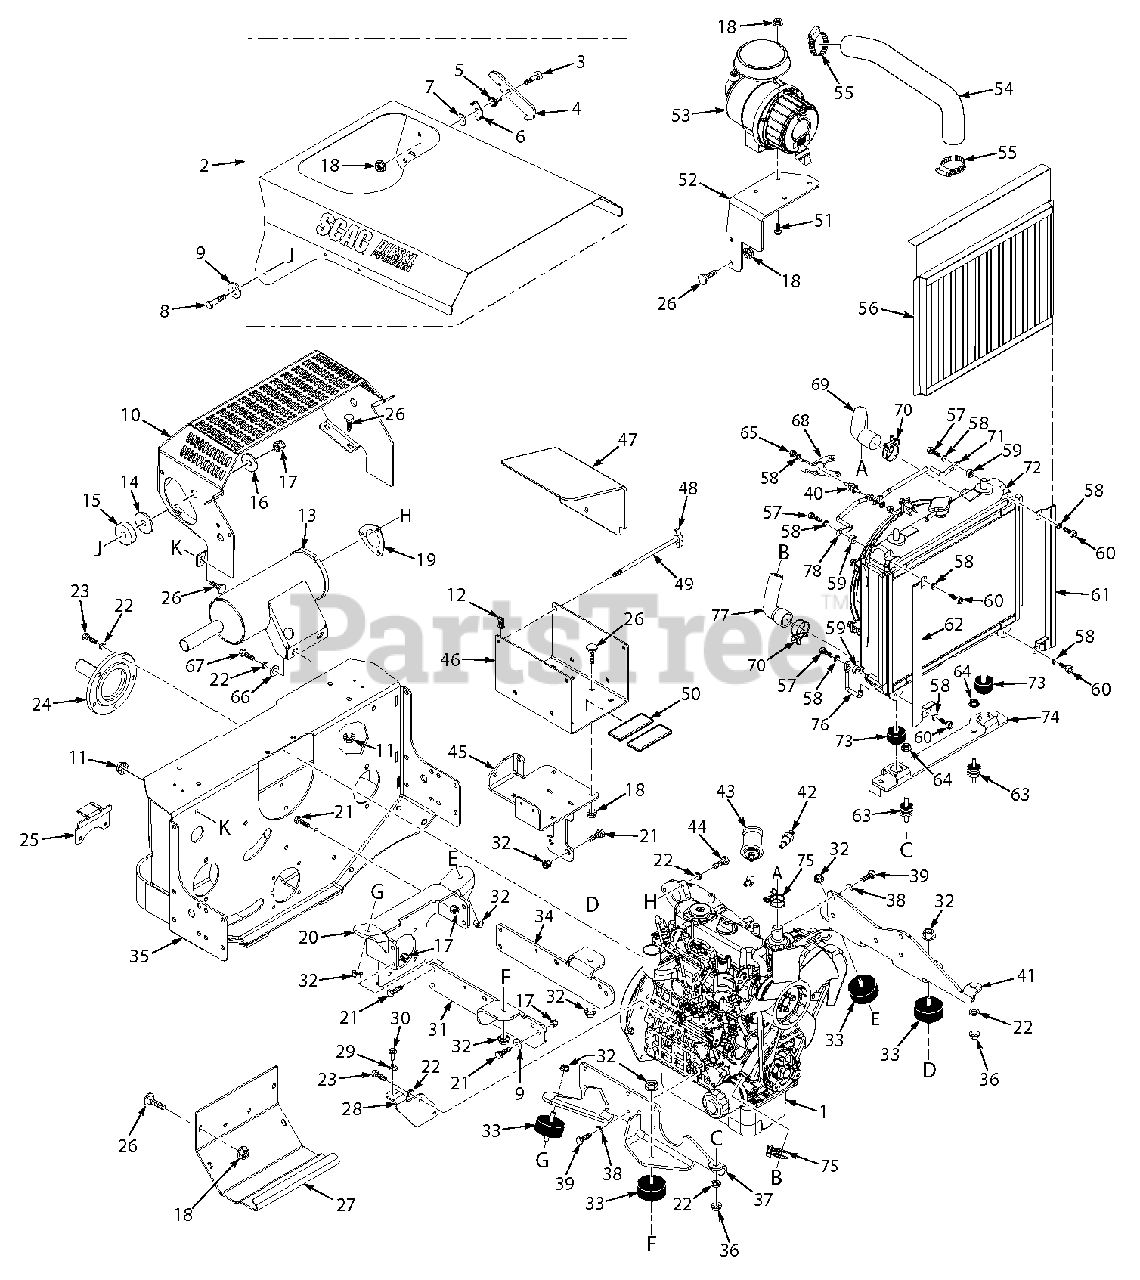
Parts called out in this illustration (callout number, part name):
1	Engine, D902 - Kubota
2	Hood Assy., STTII (Kubota Diesel)
3	Bolt, Shoulder 5/16-18 x 1/2"
4	Latch, Hood
5	Spring, Hood Latch
6	Lock, Hood Latch
7	Flatwasher, 3/8-.406 x .812 x .065
8	Bolt, Hex Head, 3/8-16 x 1-3/4"
9	Flatwasher, 3/8-.391 x .938 x .105
10	Guard, Muffler
11	Nut, Flange Elastic Stop Nut, 5/16-18
12	U-Nut 1/4-20
13	Muffler, Kubota
14	Disc, Anti-Friction
15	Spacer, Hood
16	Flatwasher, 3/8 (.406 x 1.50 x 7 Ga.)
17	Nut, Elastic Stop 3/8-16
18	Nut, Serr. Flng. 5/16-18
19	Gasket, Muffler
20	Plate, Rear Engine Mount
21	Bolt, Hex Hd. 3/8-16 x 1"
22	Lockwasher, 5/16" Spring
23	Bolt, Metric Hex Hd. M8-1.25 x 20mm
24	Stub Shaft, (Kubota)
25	Bracket, Belt Guide
26	Bolt, Carriage 5/16-18 x 3/4"
27	Cover, Rear
28	Bracket, Control Mount
29	Clamp
30	Screw, Self Tapping
31	Plate, Engine Mount RH
32	Nut, Serr. Flng. 5/16-18
33	ISO Mount
34	Plate, Engine Mount LH
35	Pump Mounting Plate Weldment
36	Nut, Metric Hex M8-1.25mm
37	Mounting Bracket Weldment RH
38	Lockwasher, 7/16" Spring
39	Bolt, Metric Hex Hd. M10-1.25 x 25mm
40	ISO Mount, Upper Radiator
41	Mounting Bracket Weldment LH
42	Sender Unit, Water Temperature
43	Sender Unit, Oil Pressure
44	Bolt, Metric Hex Hd. M8-1.25 x 30mm
45	Battery Bracket Weldment
46	Battery Box w/Decal
47	Cover, Battery
48	Knob, 1/4" Wing
49	Bolt, Hex Head 1/4-20 x 8"
50	Rubber Pad
51	Bolt, Hex Head Serr. Flng 5/16-18 x 1"
52	Bracket, Air Cleaner Mount
53	Air Filter Assembly (Enginaire p/n 67150)
54	Hose, Air Intake
55	Clamp, 2-3/4" Max. Dia.
56	Debris Screen Assembly (With Upper Foam)
57	Bolt, Metric Hex Hd. M6-1.0 x 30mm
58	Lockwasher, 1/4" Spring
59	Spacer, Radiator
60	Capscrew, Metric M6-1.0 x 16mm
61	Debris Screen Track RH
62	Debris Screen Track LH
63	ISO Mount, Lower Radiator
64	Nut, Metric Serr. Flng. M8 x 1.25
65	Nut, Metric Hex M6 x 1
66	Flatwasher, SAE 5/16 (.344 x .688 x .065")
67	Bolt, Metric Hex Hd. M8-1.25 x 25mm
